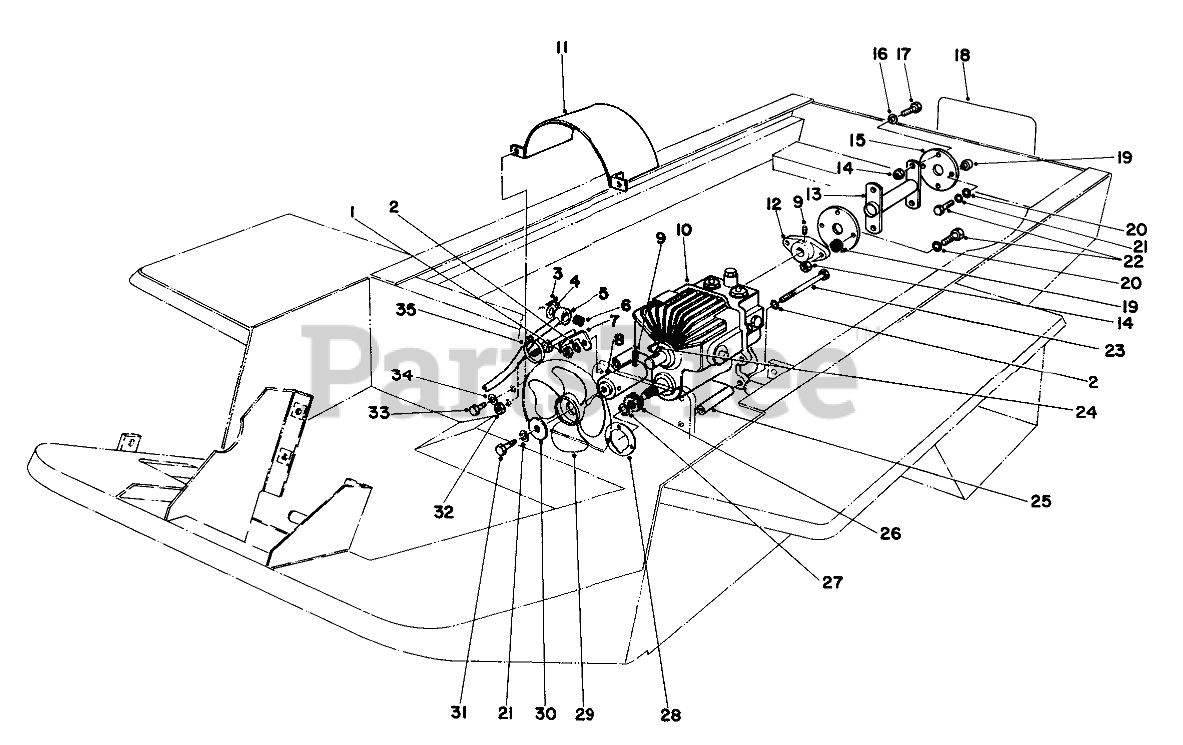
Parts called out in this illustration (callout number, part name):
1	NUT-HEX
2	WASHER-LOCK
3	PIN-COTTER
4	WASHER-FLAT
5	PUMP CONTROL TUBE WA
6	BUSHING-RUBBER
7	Axle Support
8	Hub & Plug
9	SCREW-SET, HSH
10	Transmission
11	Fan Shroud
12	Pump Hub
13	Drive Shaft
14	NUT-HEX
15	COUPLING-RUBBER
16	SPACER-COUPLING
17	SCREW-HH
18	Decal-Toro
19	SPACER-RUBBER COUPLNG
20	WASHER-FLAT
21	WASHER-LOCK
22	SCREW-HH
23	SCREW-HH
24	KEY-WOODRUFF
25	SPACER-MOUNTING
26	Gear
27	Ring-Snap
28	GASKET-TRANSMISSION
30	Washer
31	SCREW-HH
32	NUT-JAM
33	SCREW-HH
34	WASHER-LOCK
35	TIE-CABLE
